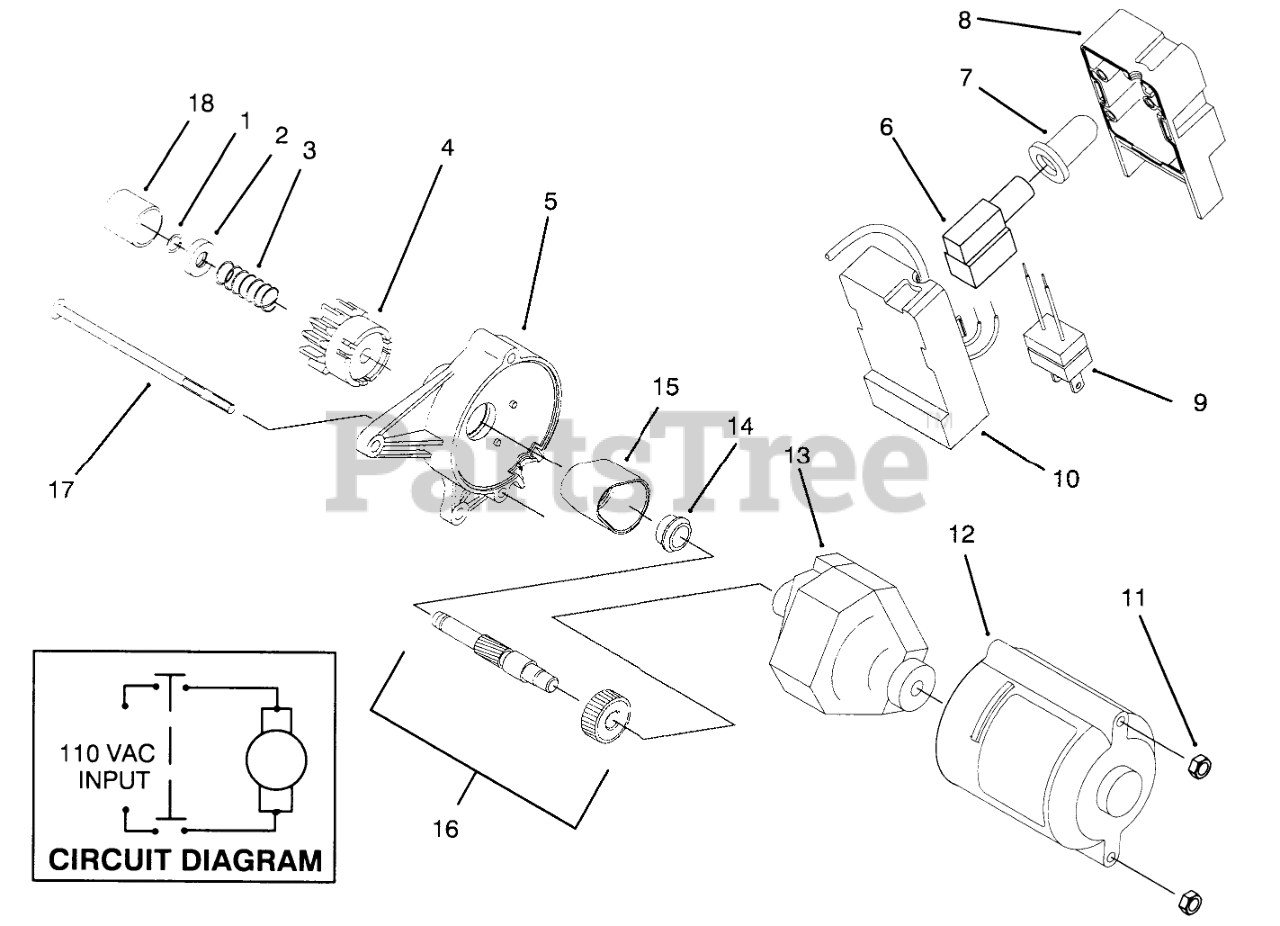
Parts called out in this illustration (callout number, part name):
1	RING-LOCK
2	PINION STOP
3	SPRING
4	PINION ASM
5	Housing-Starter
6	SWITCH-STARTER
7	BOOT-SWITCH
8	Cap-Switch Housing
9	Plug
10	OBS BASE X
11	NUT-LOCK, NI
12	HOUSING COVER
13	STARTER MOTOR ASM
14	BUSHING
15	COVER-GEAR
16	Asm-shaft & Gear
18	CAP-PINION
